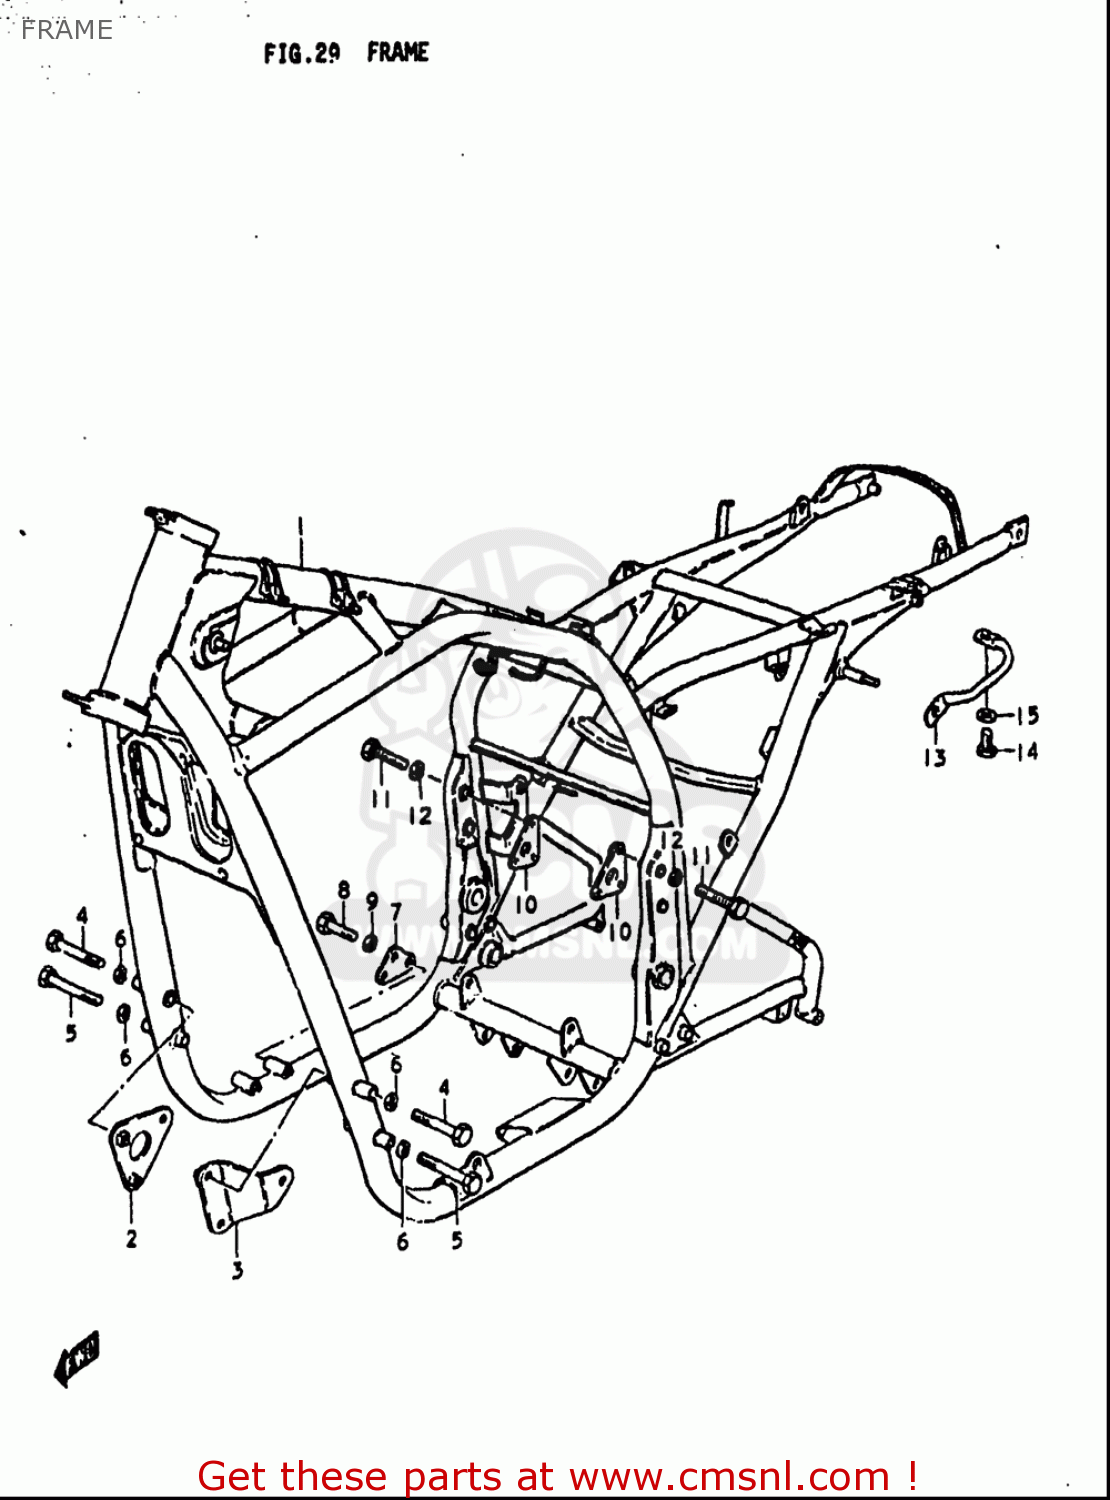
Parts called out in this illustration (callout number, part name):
4	BOLT
5	BOLT
6	WASHER,LOCK
7	PLATE,ENG MTG NO.2
8	BOLT
9	WASHER,LOCK
10	PLATE,ENG MTG NO.4
11	BOLT
12	WASHER,LOCK
13	GRIP,FRAME HANDLE
14	BOLT
15	WASHER
